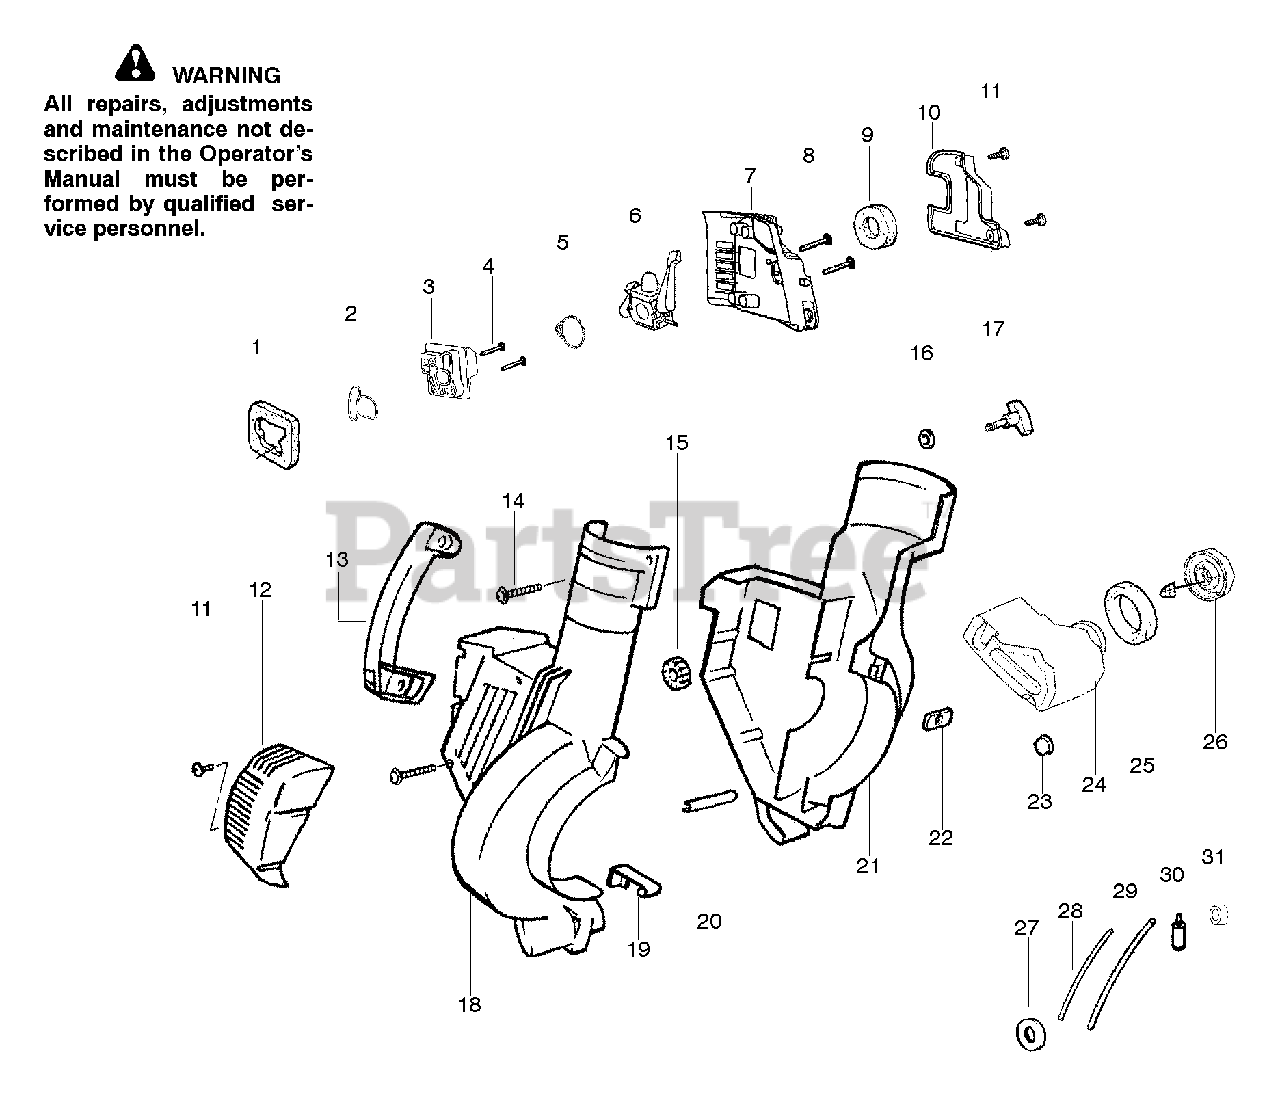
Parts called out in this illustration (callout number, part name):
1	Air Dam (kit)
2	Gasket- Adapter (kit)
3	Carburetor Adaptor
5	Gasket-Carburetor (kit)
6	Kit-Carb Ass'y (C1Q-W11)
6	Kit-Carb Ass'y (C1Q-W11C)
6	Kit-Carb Ass'y (WT-606)
8	Screw-Carb.
9	Filter-Air
10	Cover-Air Filter
12	Guard-Muffler
15	Isolator
17	Knob-Blower
18	Housing-Right
19	Spring-Cover Latch
20	Guide-Starter Rope
21	Housing-Left
23	Isolator-Crankcase
24	Assy-Fuel Tank
25	Gasket-Fuel Tank
26	Fuel Cap w/Retainer
27	Grommet-Shroud
28	Kit-Line Carb/Purge
29	Kit-Line Tank/Purge
30	Assy-Fuel Pick-up
31	Grommet-Fuel line (kit)
